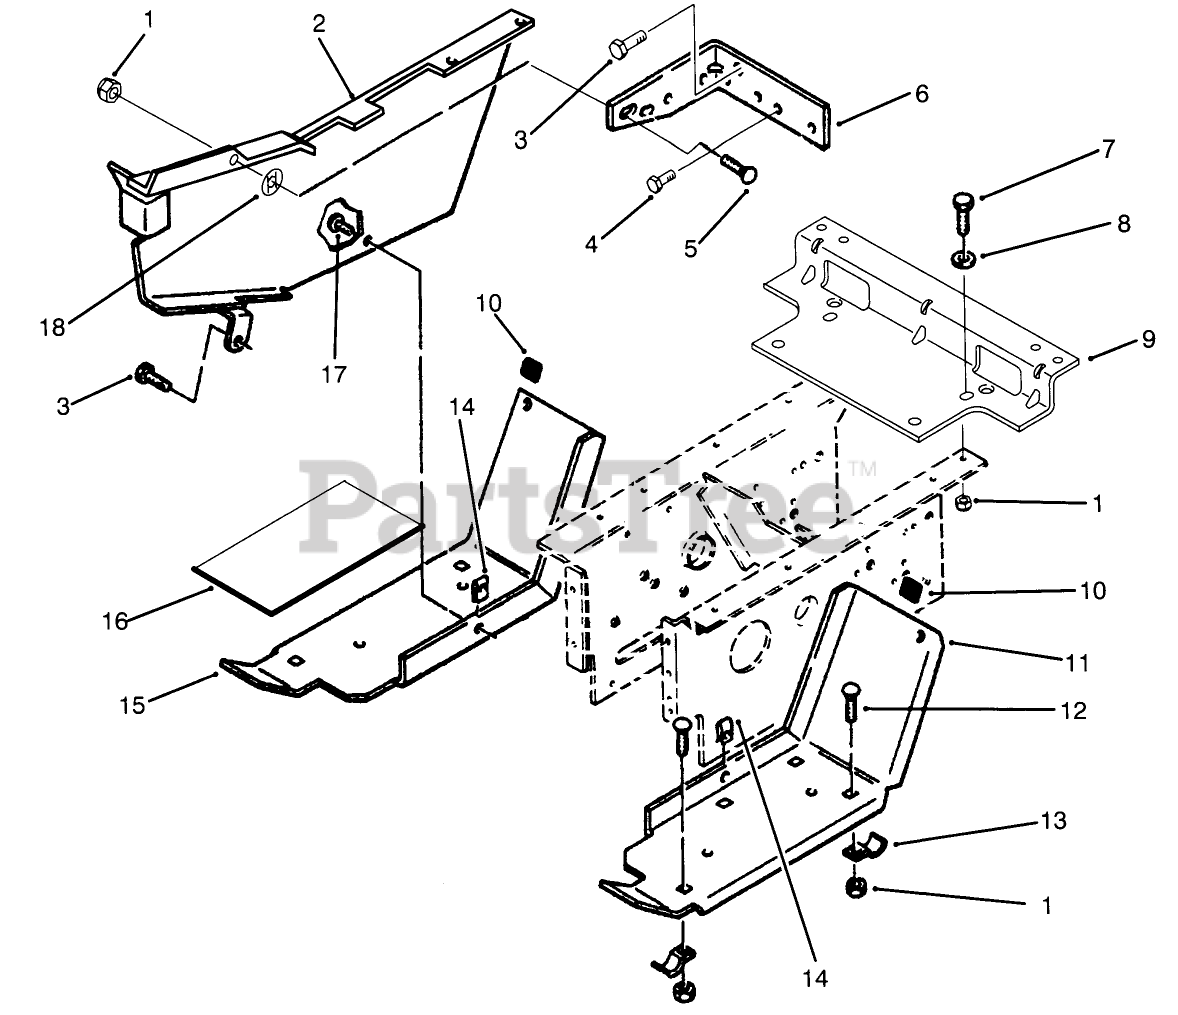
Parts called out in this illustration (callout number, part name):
1	NUT-LOCK, NI
2	GUARD - BELT WA *R
3	SCREW
4	Bolt
5	BOLT-CARR
6	BRACKET-BELT*B
7	SCREW-HH
8	WASHER-PLAIN
10	BUMPER
11	FOOTREST LH *R
12	BOLT-CARR
13	BRACKET
16	PAD FOOTREST
